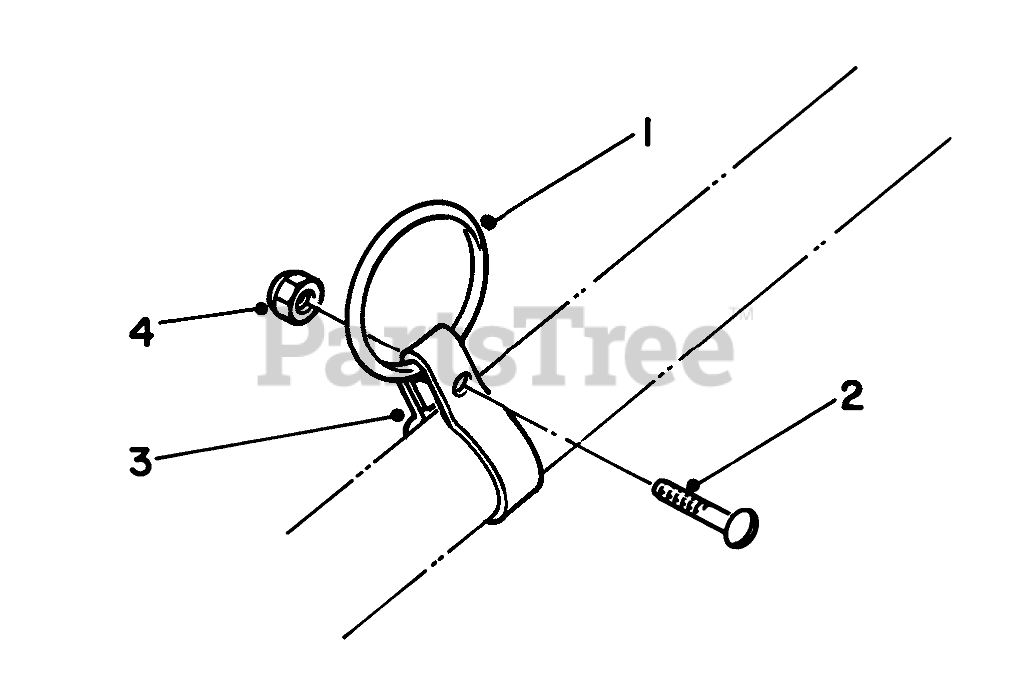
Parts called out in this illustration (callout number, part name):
1	RING-HARNESS
2	SCREW-SRH
3	HARNESS CLAMP
4	NUT-LOCK, NI
